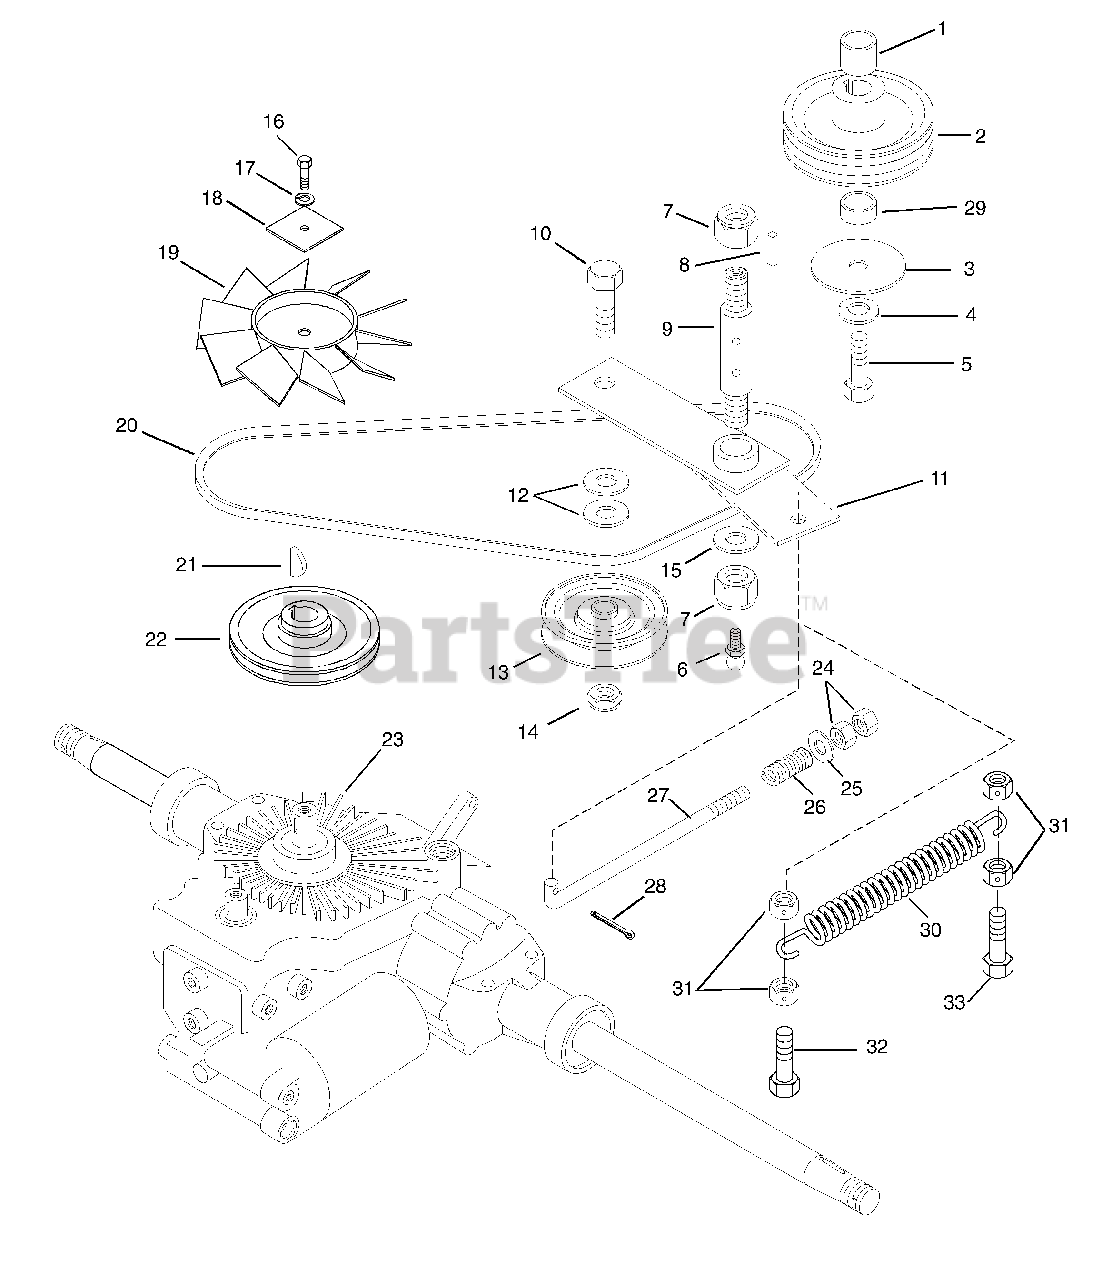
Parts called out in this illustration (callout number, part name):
1	Bushing-Sleeve 1.13 x 1.38 x 1.25 (015)
3	Washer-Special .469 x 2.000 x .250
4	Washer-Locking .44 x 1.09
5	Bolt-Hex .44-20 x 1.50
6	Fitting-Lube 1/8
7	Nut-Locking-Center .62-11
8	Key-Square .248 x 1.25 x .248
9	Pin-Pivot
10	Bolt-Hex .38-16 x .50 Grade 5
11	Weldment-Idler Arm
12	Washer-Flat-Steel .531 x 1.06 x .095
13	Pulley-V 4.00 x .84
14	Nut-Locking-Center .50-13
15	Washer-Flat-Steel .656 x 1.31 x .095
16	Bolt-Hex .25-20 x 1.25 Grade 5
17	Washer-Lock .25 x .062
18	Washer-Flat-Steel .265 x 1.75 Square x .119
19	Fan
20	V-Belt A-Section 18.05 x .495
21	Key-Woodruff .19 x .63
22	Pulley-Drive
23	Transaxle-Eaton #851-109
24	Nut-Hex .375-16
25	Washer-Flat-Steel .406 x .812 x .065
26	Spring-Compression .072 x .561 x 2.50
27	Rod-Idler
28	Pin-Cotter .09 x .75
29	Spacer 1.137 x 1.50 x .656
30	Spring-Extension
31	Nut-Locking Center .38-16
32	Bolt-Hex .38-16 x 1.50
33	Bolt-Hex .38-16 x 2.00 Grade 5
